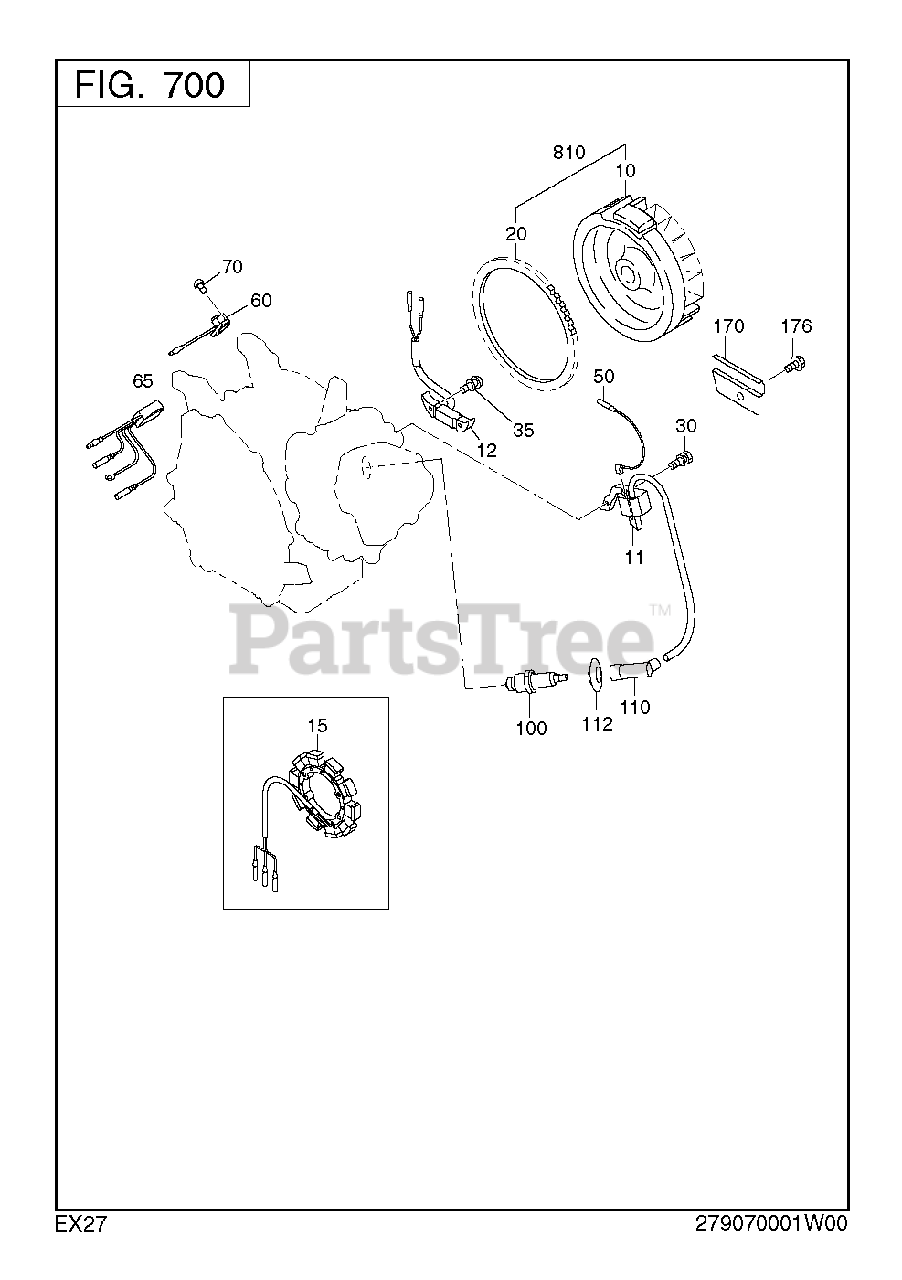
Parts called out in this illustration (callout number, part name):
10	FLYWHEEL CP
11	IGNITION COIL CP
20	RING GEAR
30	BOLT AND WASHER AY
35	BOLT AND WASHER AY
50	WIRE 5 CP
100	SPARK PLUG
110	SPARK PLUG CAP
